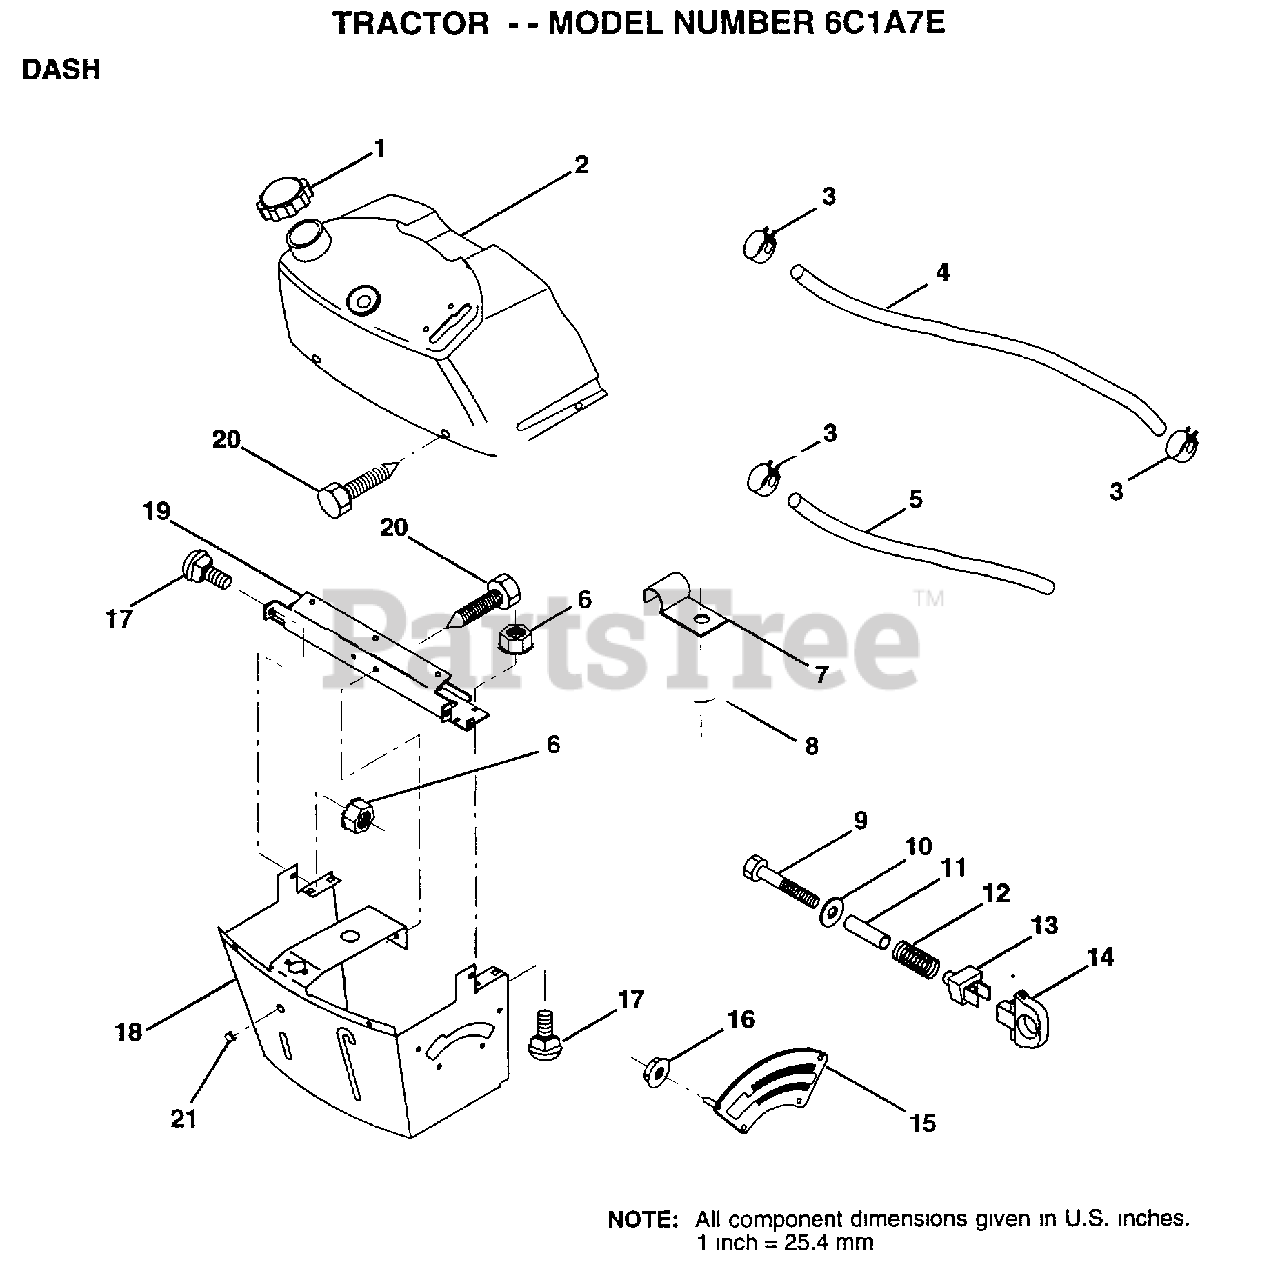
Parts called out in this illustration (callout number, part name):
1	CAP BLK FUEL LR
2	TANK.ASM.DASH.LR
3	HOSE CLAMP
5	FUEL LINE T
6	NUT HXKEP 1/4X20
7	CLIP T
8	WASHER PM
9	BOLT
11	SPACER SPLIT
12	SPRING M
13	"KNOB,HGT RETAINER"
14	KNOB
15	ADJUSTER QUAD
16	NUT
17	BOLT
18	SUPT ASSY DASH
19	CROSS BRACE
20	SCREW.1/4-20X1/2
21	PLUG DOME
